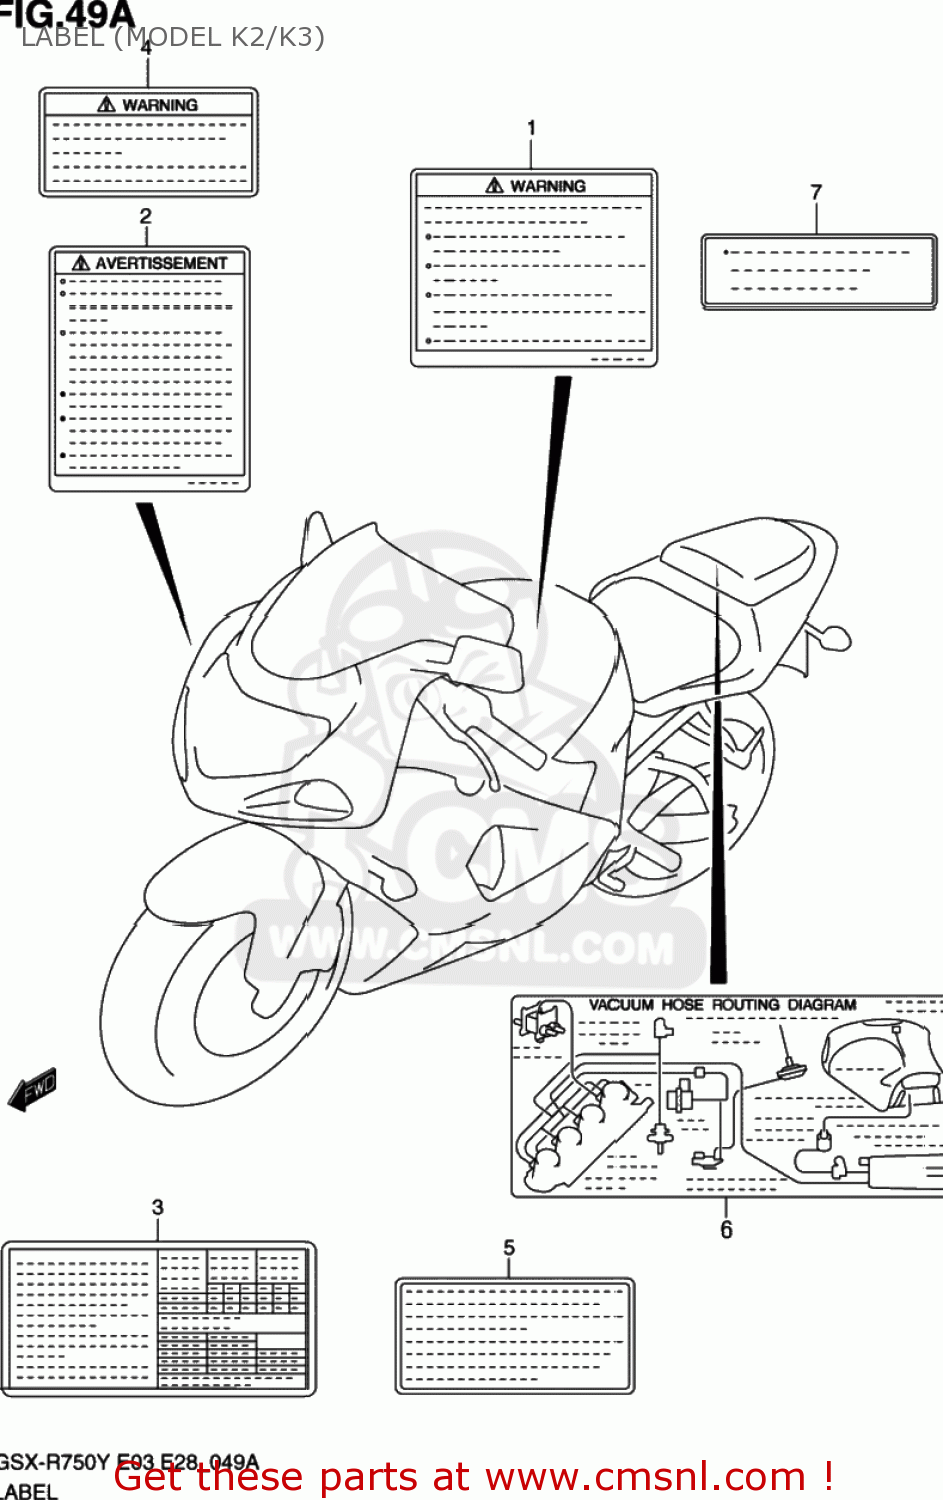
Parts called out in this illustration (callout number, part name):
1	LABEL,GENERAL WARNING
2	LABEL,SCREEN
3	LABEL,TIRE INFORMATION
4	LABEL,WARNING STEERING
5	LABEL,MANUAL NOTICE
6	LABEL,VACUUM HOSE ROUTING
7	LABEL,FUEL INFORMATION
8	MANUAL,OWNER'S
